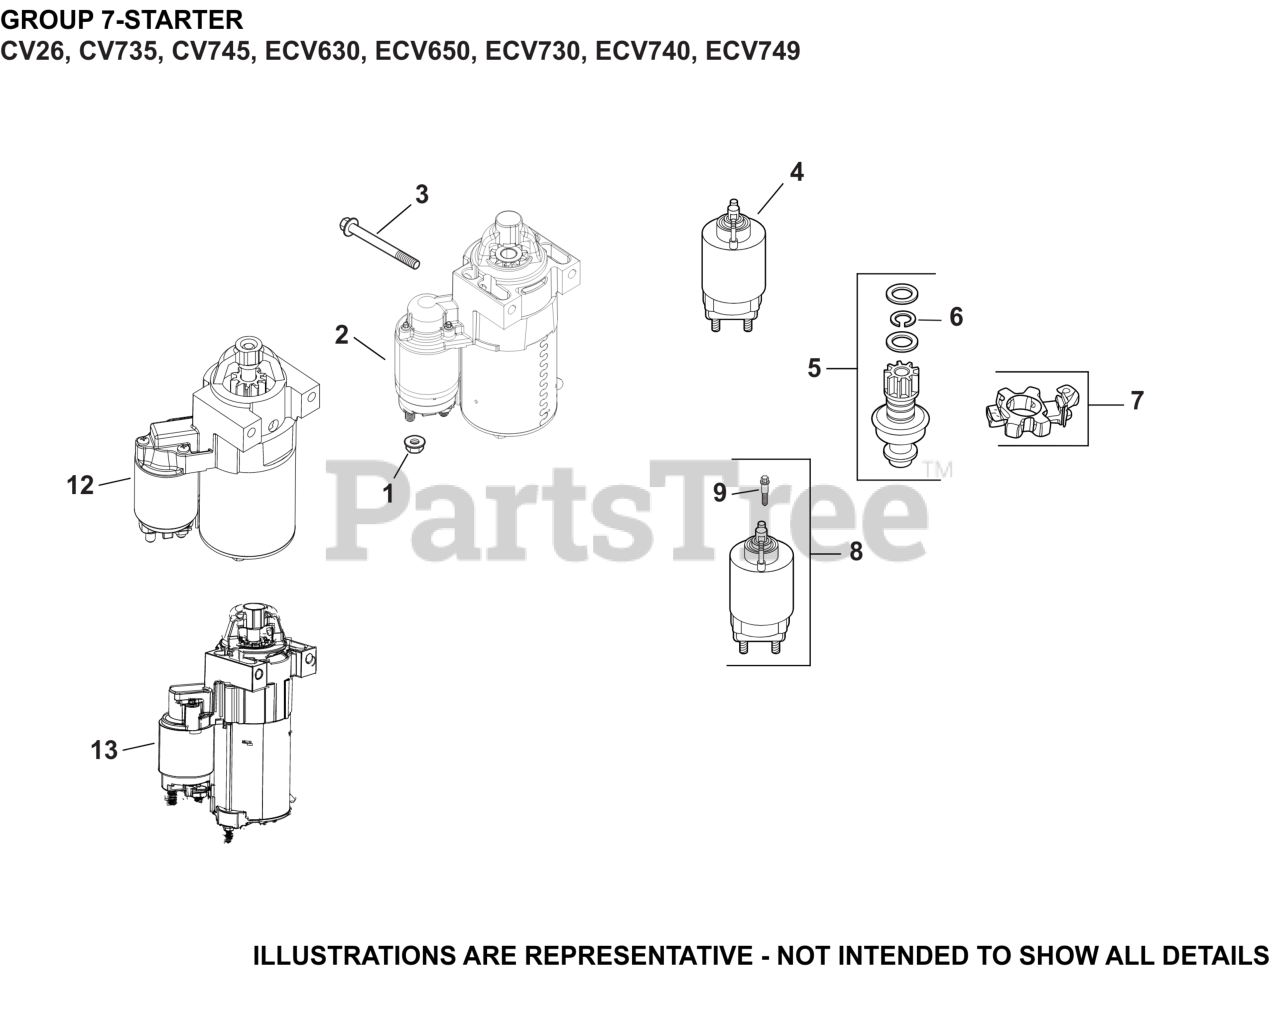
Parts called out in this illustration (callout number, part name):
1	NUT, FLG M8X1.25
2	STARTER, SOLENOID SHIFT
3	SCREW, FLG M8X1.25X80
